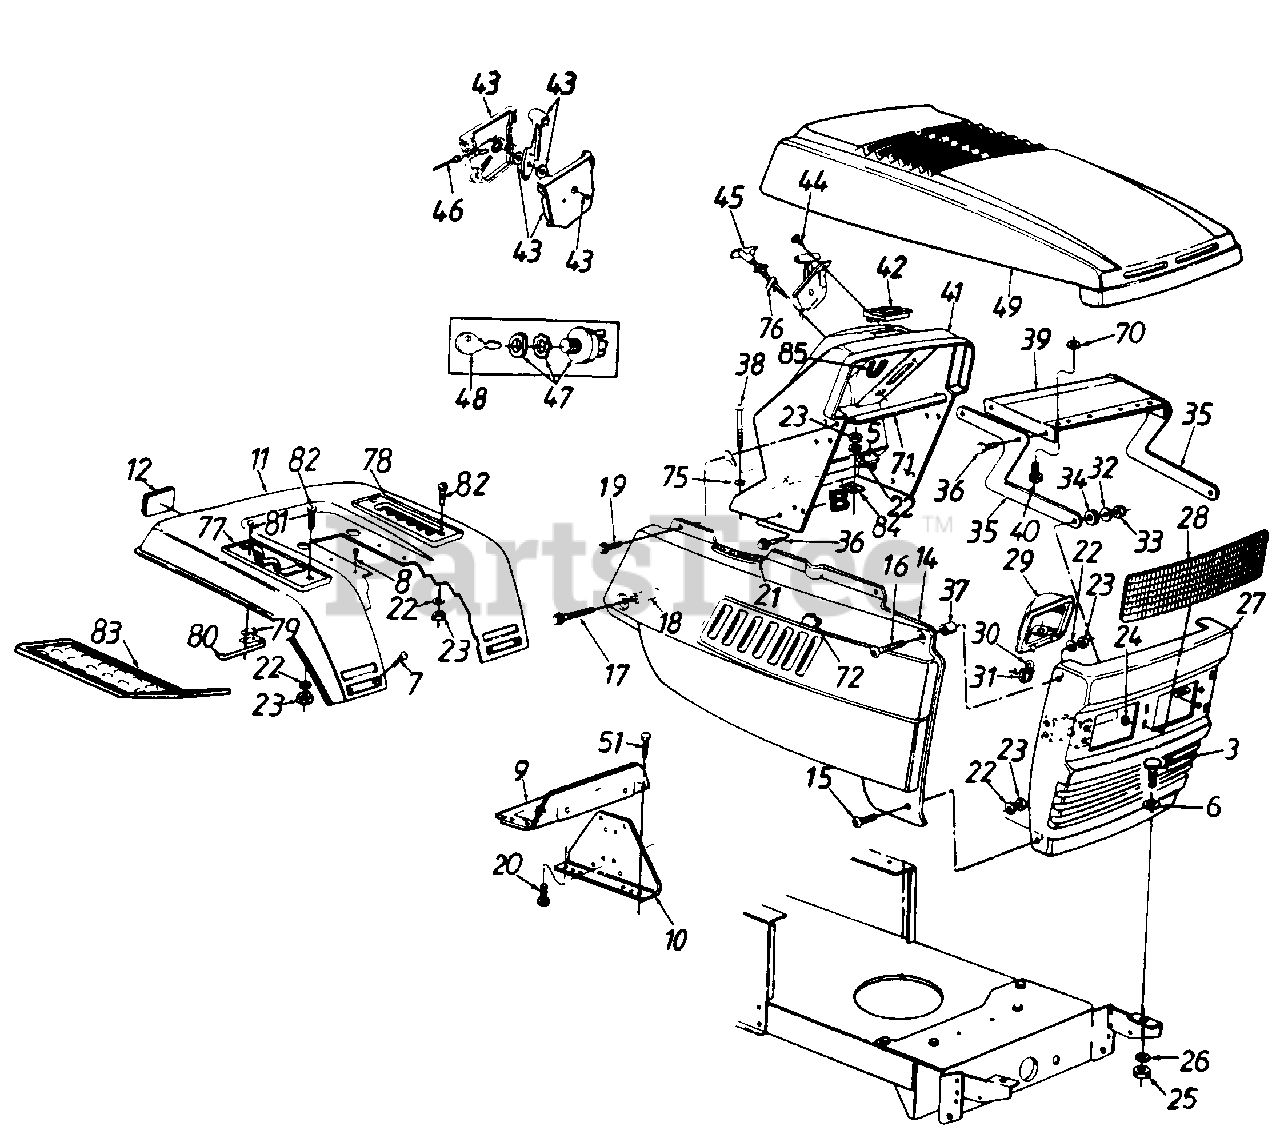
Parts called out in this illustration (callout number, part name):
3	Hex Bolt 5/16-18 x .75" Lg.
5	Light Switch
6	Fl-Wash. .344" I.D. x 1" O.D.
7	Carriage Bolt 1/4-20 x .5" Lg.
8	Hex Wash. Hd. Tap Scr. 5/16 x .75" Lg.
9	Support Bracket
14	Side Panel - R.H.
15	Truss Mach. Scr. 1/4-20 x .5" Lg.
16	Truss Mach. Scr. 1/4-20 x 1.0" Lg.
17	Hex Wash. TT-Tap Scr. 1/4-20 x 1.75" Lg.
18	Spacer .26" I.D. x 1.32"
19	Hex Rolling Tap Scr. 1/4-20 x .75" Lg.
20	Hex Bolt 1/4-20 x .62" Lg.
21	Trim Strip - 18" Lg.
22	L-Wash. 1/4" I.D.
23	Hex Nut 1/4-20 Thd.
24	Speed Nut 5/16" Thd.
29	Headlamp Housing
30	Headlamp
31	Twist Lock Lamp Socket
32	Bell-Wash. .345" I.D. x .88"
33	Hex L-Nut 5/16-18 Thd.
34	Rubber Washer
37	Spacer .262" I.D. x .3"
38	Carriage Bolt 1/4-20 x 1.25" Lg.
41	Dash
42	Ammeter
43	Throttle Control Box Ass'y
44	Mach. Scr. #10 x .44" Lg.
45	Choke Control
46	Throttle Control Wire
47	Ignition Switch
48	Ignition Key
49	Hood
51	Hex Wash. Hd. B-Tap Scr. 5/16-18 x .5" Lg.
70	Fl-Wash. .406" I.D. x .812" O.D.
71	Grille Support Tube
75	Retaining Nut
76	Choke Retainer
77	Forward/Reverse Index Brkt.
78	7-Speed Index Brkt.
79	Insulator Nut Plate
80	Reverse Safety Switch
81	Hex Wash. Hd. AB-Tap Scr #8 x .5" Lg.
82	Truss Mach. Scr. 1/4-20 x 75" Lg.
83	Rubber Foot Pad - L.H.
84	Dash Fastening Tab
85	Cable Tie
